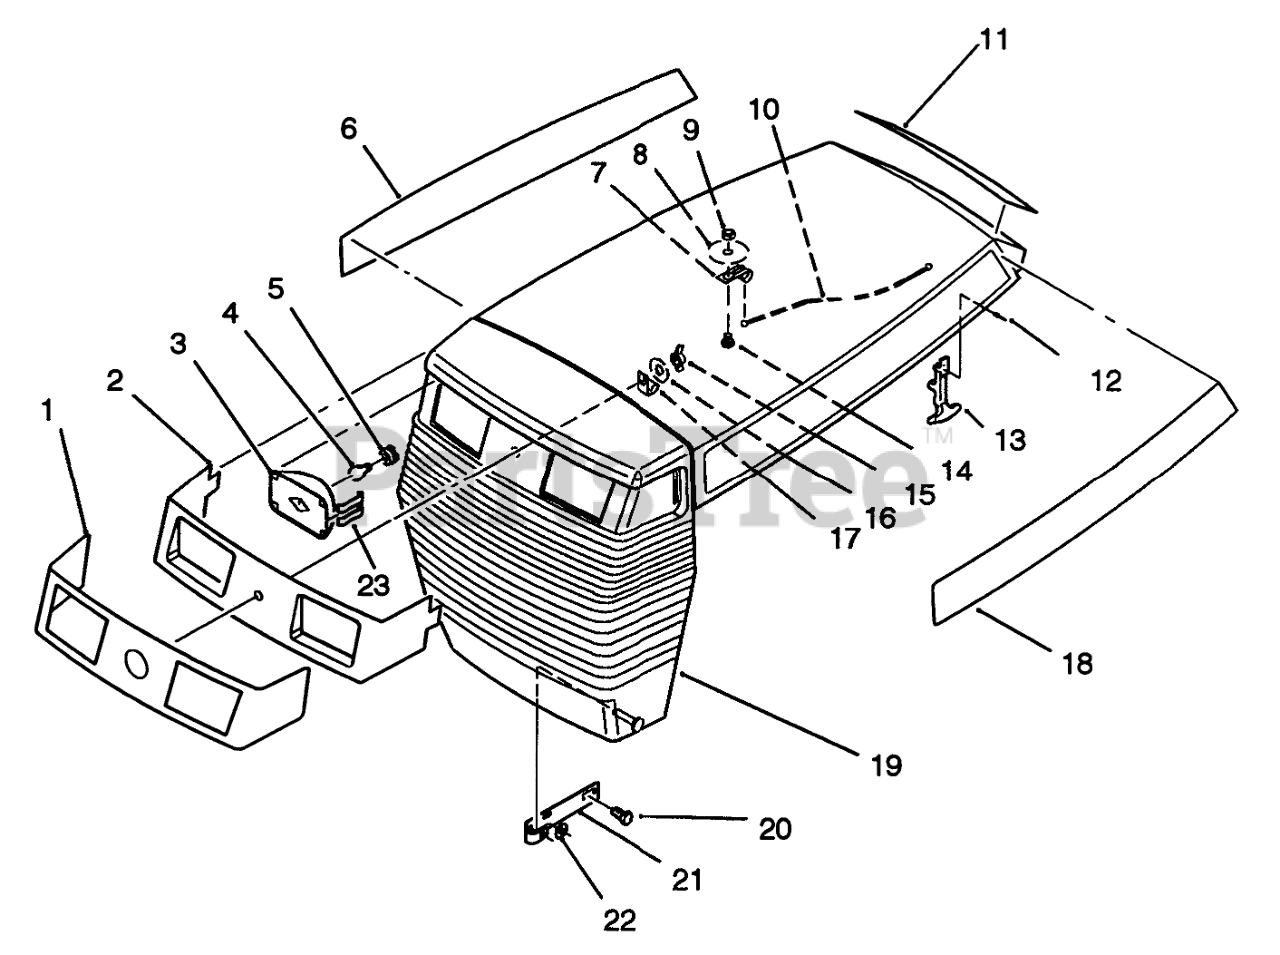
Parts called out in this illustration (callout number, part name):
1	DECAL-FRONT HOOD
2	LIGHT-BAR BLACK
3	LIGHT POD
4	BULB
5	SOCKET-HEADLIGHT
6	DECAL HOOD RH
7	CLEVIS
8	WASHER-BACKING
9	Nut
10	CABLE-ASS'Y
11	Decal-Hood Rear
12	RIVET-POP
13	HANDLE ASM
14	SCREW
15	WING NUT
16	WASHER
17	J-CLIP
18	DECAL-HOOD L.H. 246H
19	Hood
20	Screw
21	BRKT-HOOD MTG L.H R
22	PUSH-NUT 5/16
23	RETAINER
